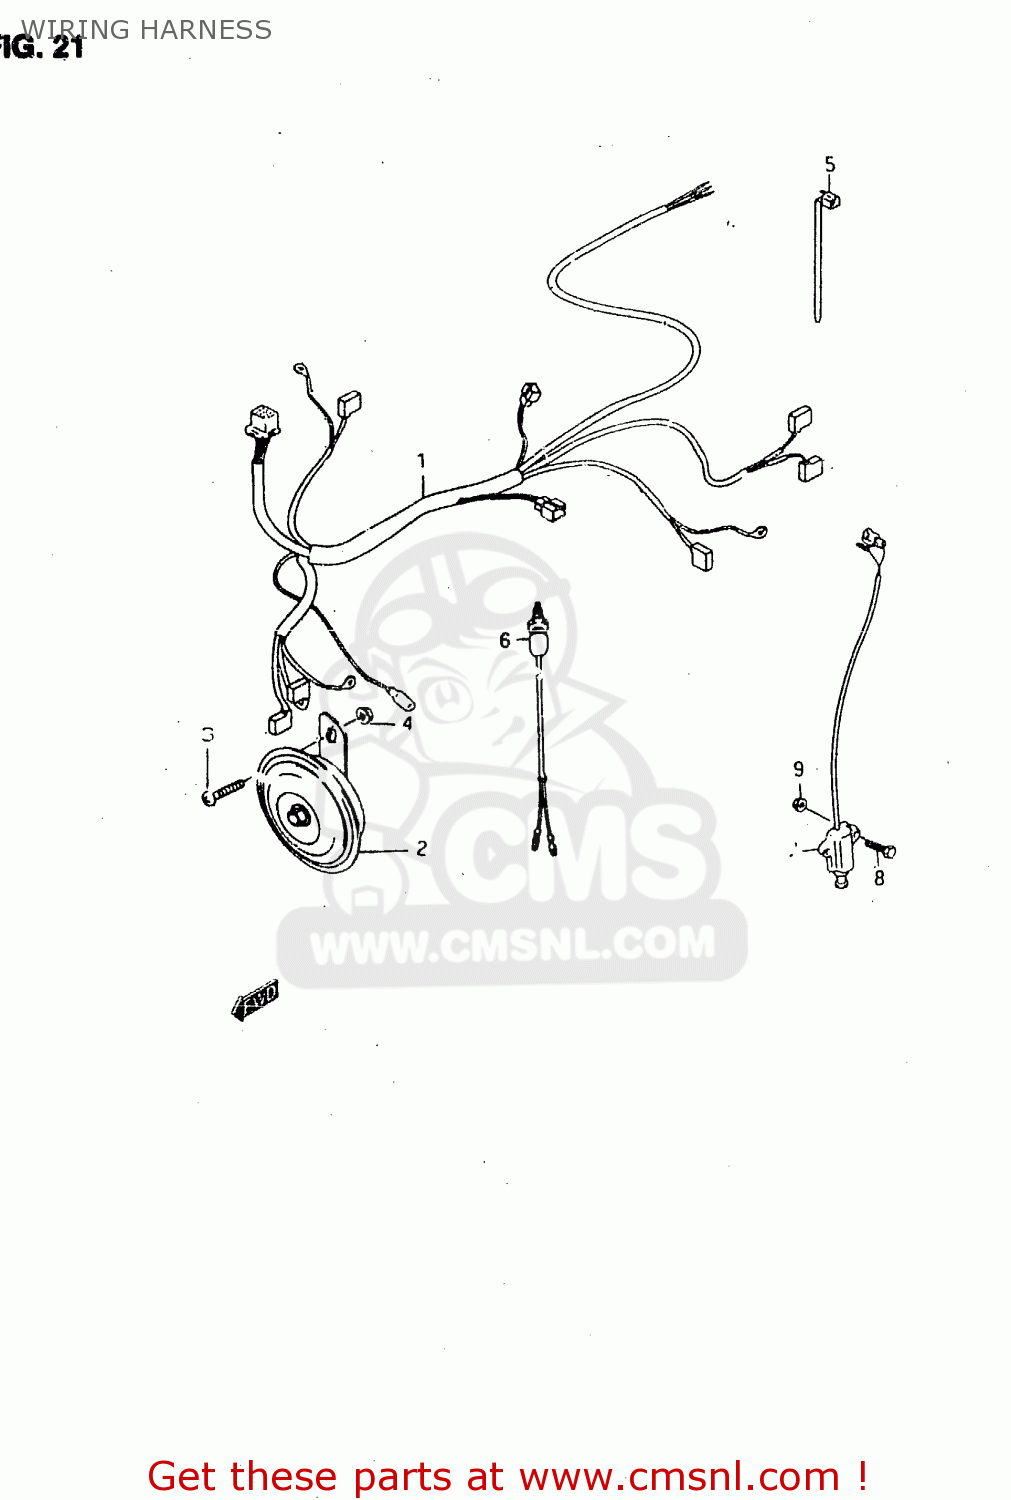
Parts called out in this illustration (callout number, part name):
1	HARNESS, WIRING
2	HORN ASSY
3	SCREW 6X16
4	NUT
5	CLAMP(L:125)
6	SWITCH ASSY, STOP
7	SWITCH ASSEMBLY,SIDE STAND
8	BOLT
9	NUT
